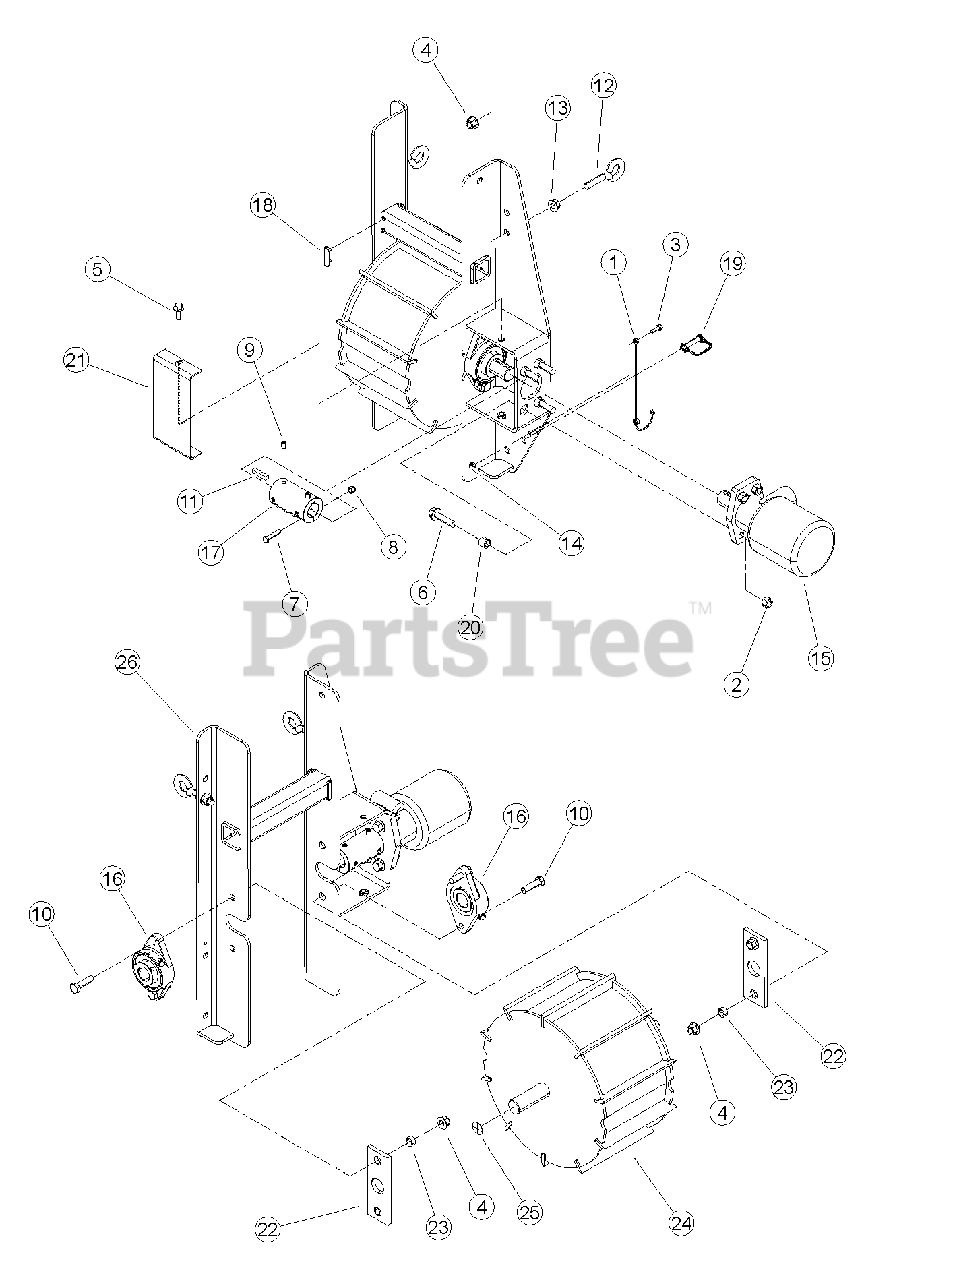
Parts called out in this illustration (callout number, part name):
1	LANYARD, NYLON
2	NUT, 1/2" CENTERLOCK GRB ZP
3	BOLT, 1/4-20 X 3/4 HWH GR5 CZP
4	NUT, 1/2-13 NYLOCK FLANGE
5	BOLT, 3/8 X 1 FLANGE NC
6	BOLT, 1/2-13 X 2 HWH GR5 CZP
7	BOLT, 5/16 X 1-1/2 GR5 HEX CPS ZP
8	NUT, 5/16" NE NYLOCK ZP
9	SET SCREW, 3/8 X 1/2 CUP PT SKT
10	BOLT, 1/2 X 1 3/4 GR5 HCPS NC ZP
11	KEY, 5/16 X 1-1/2 SQUARE
12	EYEBOLT, 1/2 X 2" ZP
13	NUT, 1/2 SPIRAL LOCK NC ZP
14	NUT, 1/4-20 NYLOCK-FLANGE
15	MOTOR, 45 CU IN HYDRAULIC
16	BEARING, 1-1/4" DIA 2 BOLT FLANGE
17	COUPLER, 1-1/4 SHAFT
18	WEAR PAD, STD. SPRING HD FRONT
19	PIN, SNAP 3/8 X 1-1/2 USABLE LGH
20	SPACER, 0.75 X 0.620
21	SHIELD, COUPLER
22	BEARING, SLIDE
23	SPACER, .75 OD X .5 ID X .37
24	ASSEMBLY, TOP GRAB ROLLER SERVICE PART
25	DECAL, ROTATING SHAFT
26	WELDMENT, ROLLER SLIDE
